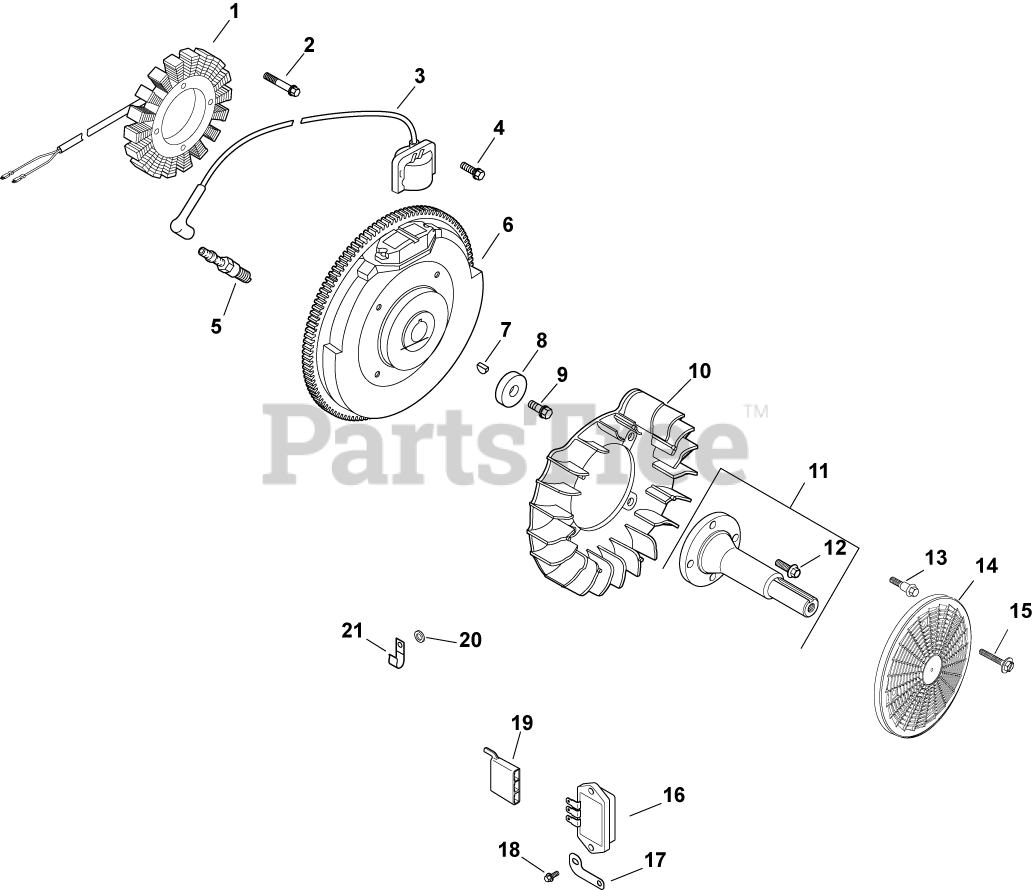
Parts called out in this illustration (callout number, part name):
1	KIT, 15 / 20 AMP STATOR
2	SCREW, THREAD FORMING
3	MODULE, MAGNETO DIGITAL IGNITION USE 25 584 14-S
4	SCREW, FLG THD FRM M5X.8X20-(#25086399S)
5	PLUG, SPARK (PRO SERIES)
6	FLYWHEEL ASSEMBLY (LW)
7	KEY, 3/16" X 5/8"
8	WASHER, FLAT 13/32"
9	SCREW, FLG M10X1.5X45 - (#25086361S)
10	FAN USE 24 755 253-S
11	SHAFT, FRONT DRIVE
12	SCREW, FLG M8X1.25X25
13	BOLT, SHOULDER
14	SCREEN, GRASS
15	SCREW, FLG SEMS M4X.7X25
16	REGULATOR/RECTIFIER
17	BRACKET, GROUND STRAP USE 24 518 12-S
18	SCREW, HEX FLANGE HI-LO
19	CONNECTOR
20	WASHER, FLAT 1/4" (O.D. 1/2")
21	CLIP, CABLE
